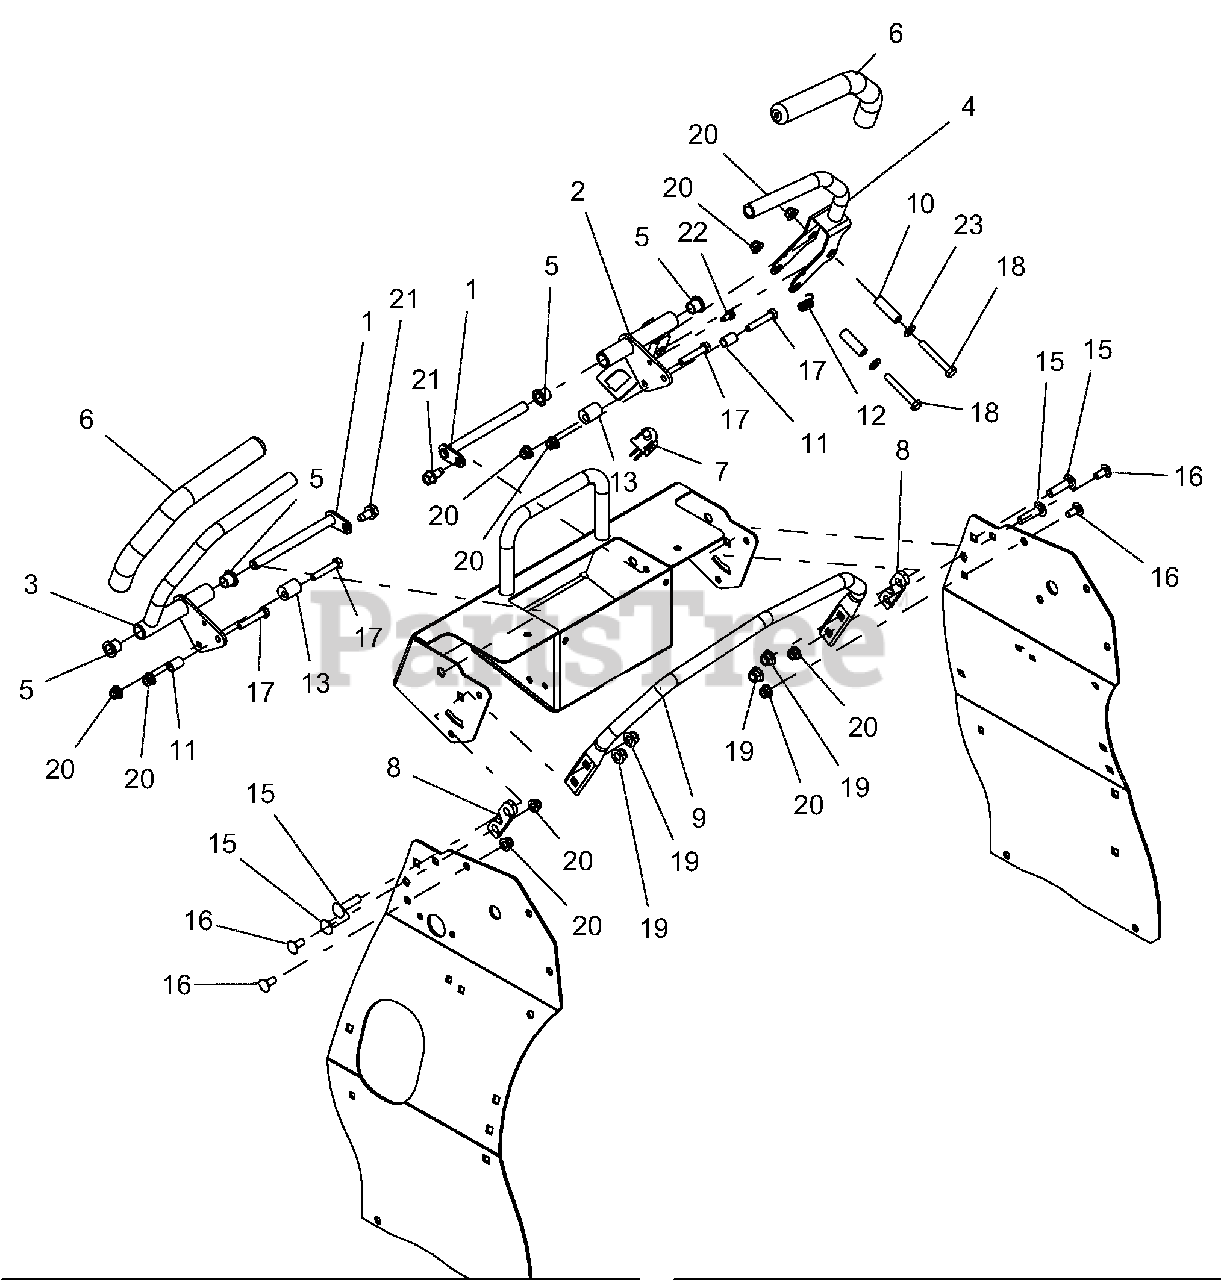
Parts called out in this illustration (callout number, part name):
1	WLDT, PIN AND LOCK
2	WLDMT, CONTROL MOUNT (LH)-BLACK
3	WLDMT, CONTROL ARM (RH)
4	CONTROL, ARM , LH
5	BRG, FLG .500 X .620 X .500 BRNZ
6	GRIP, HANDLEBAR REV
7	SWITCH, SEAT OVERIDE (N.O.)
8	SHIM, BAR 5 DEG SPEED-BLACK
9	STOP, FORWARD STEERING
10	BSHG, SLV .33X.50X1.56
11	BSHG-SLV .328X.50X.75
12	SPRG, EXTENSION
13	ECCENTRIC
15	BLT-RDHDSQNK .38-16X1.50 G5 Y
16	BLT-RDHDSQNK .31-18X.75 G5 YWZC
17	BLT-HEX .31-18X1.75 GR5 YWZC
18	BLT-HEX .31-18X2.25 GR5 YWZC
19	NUT-LK-NYL-FLG .38-16 YWZC
20	NUT-LK-NYL-FLG .31-18 YWZC
21	SCR-TAP .38-16X.75 HWH TR YWZ
22	SCR-TAP .25-20X.50 HWH TR YWZ
23	WSHR-FL-STL.344X.688X.065YWZC
